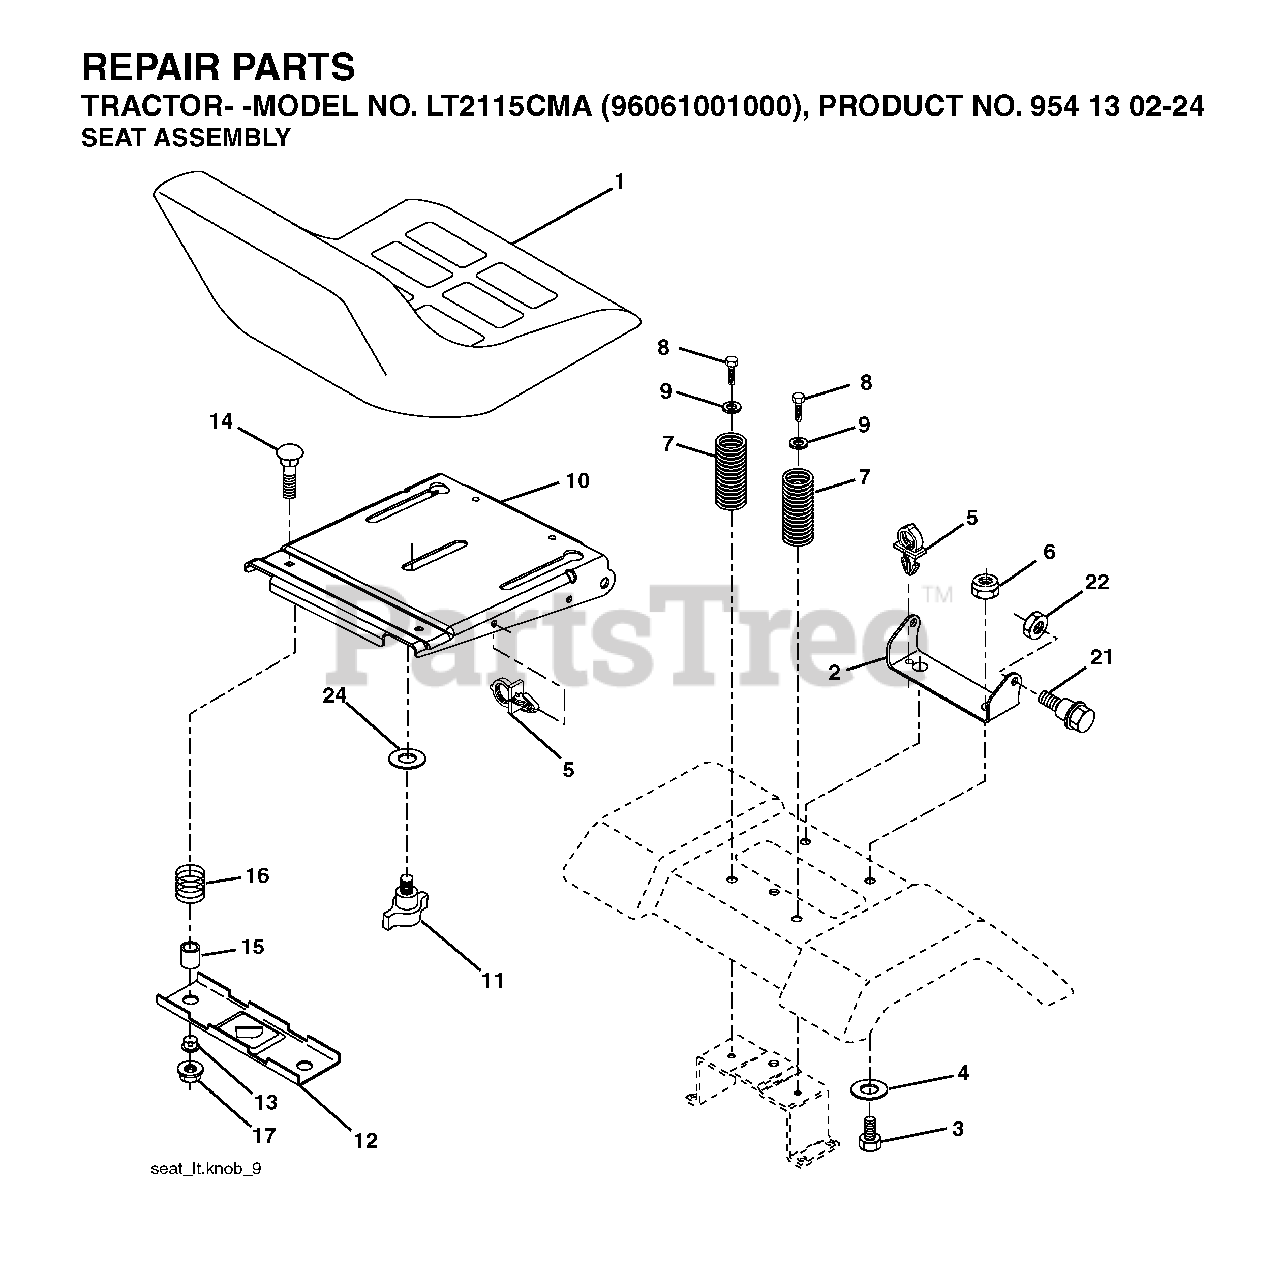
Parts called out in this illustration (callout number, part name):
2	BRKT.PIVOT.FENDER
4	WASHER PM
5	PUSH CLIP
6	NUT
7	SPRING COMPRESSION
8	SCREW 3/8-16X1
9	WASHER
11	KNOB.SEAT.ADJ.WINGNUT
12	BRKT SWITCH
14	BOLT.ROUND.HEAD.SQUARE.NECK
15	SPACER SPLIT 28X.96
17	NUT T
21	BOLT.SHOULDER.5/16-18
22	NUT.71038.31-18.HEX.NYLOCK
